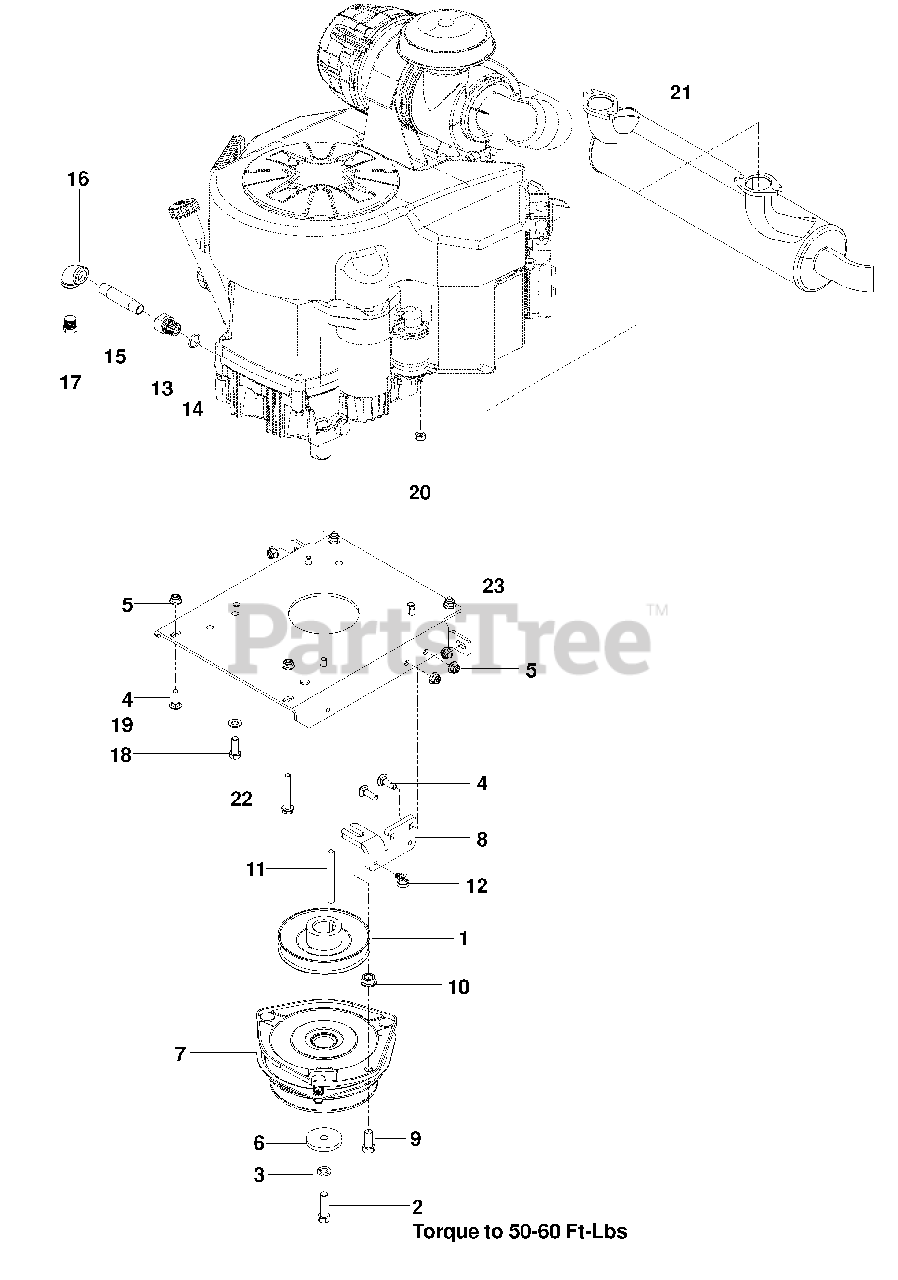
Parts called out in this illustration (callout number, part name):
1	Pulley, Engine
2	Bolt 7/16-20 X 1 1/2 Hex Nyl
3	Washer 7/16 Slw
4	Bolt 5/16-18 X 1 Rd Hd
5	Nut 5/16-18 Hex Flg Nyloc
6	Washer, Blade
7	Clutch, Gt 3.5
8	Stop, Clutch
9	Bolt 7/16-14 X 1 Hex Nyloc
10	Nut 7/16-14 Hex Whiz Lk
11	Key 1/4 Sq X 3 1/2
12	Tie Wrap W/ Clip
13	Adaptor, Oil Drain
15	Pipe 3/8 Npt X 3"
17	Plug, Drain, 3/8 Nptf
18	Bolt 3/8-16 X 1 Hex Nyloc
19	Washer 3/8 Spring
20	Nut M8 X 1.25 Nyloc
22	Screw 5/16-18 X 2 1/4 Hex Flg
23	Plate, Engine
